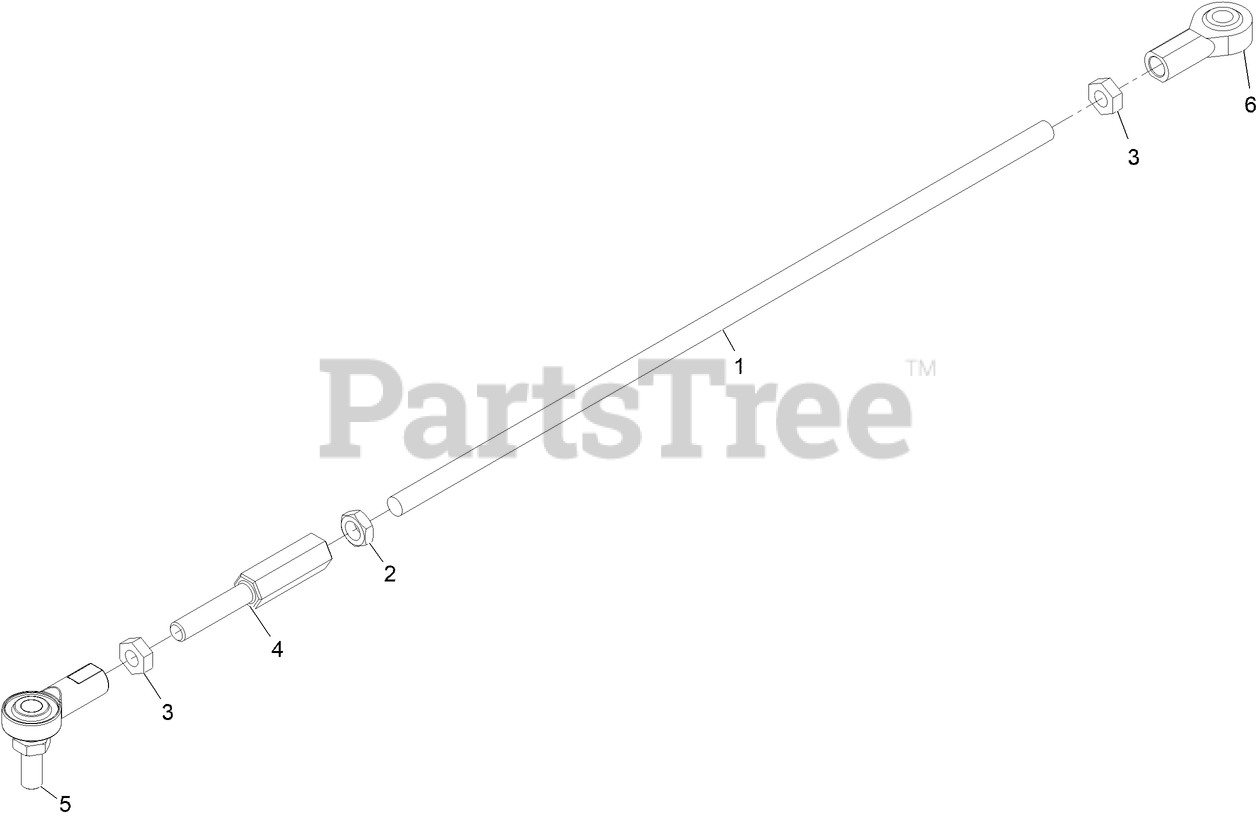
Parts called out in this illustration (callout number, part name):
1	Rod-Motion Control Short
2	NUT-JAM
3	NUT-JAM
4	ROD-ADJUST
5	BALLJOINT
6	BALLJOINT-RH
